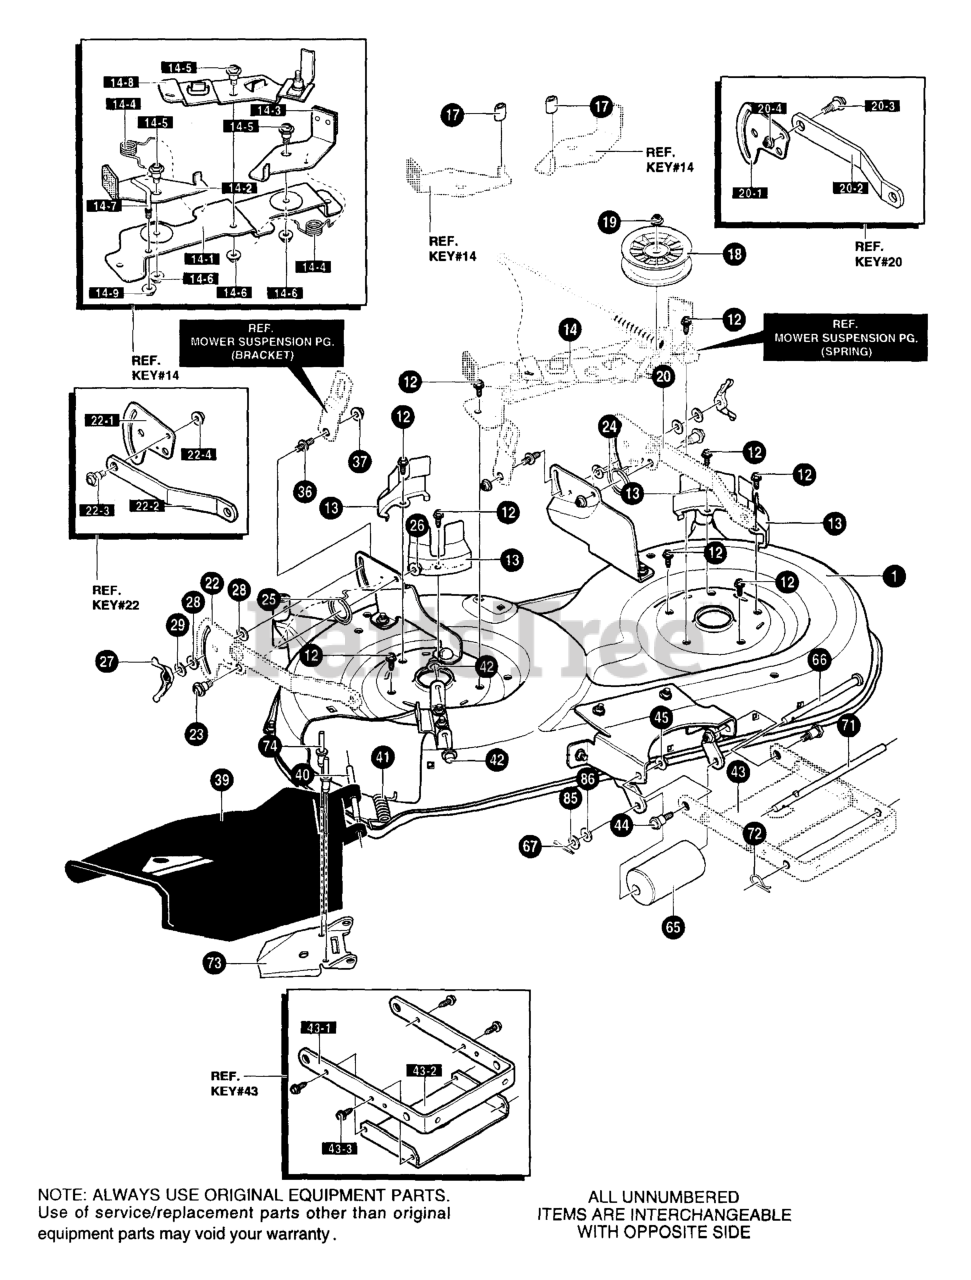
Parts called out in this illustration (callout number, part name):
1	SUB ASSY 42" MOWER DECK DELUXE
12	SCREW, 3/8-16 x 1.25 WAHHSPTAPP
13	COVER, SEGMENT BELT GUIDE
14	ASM., BRACKET SUP W/BRAKES 42"
14-1	BRACKET, BRAKE MT
14-2	ASSY, BRAKE RH
14-3	ASSY, BRAKE LH
14-4	TORSION SPRING (166X41)
14-5	BOLT.50X.75 HHSH 3/8-16 (9X39)
14-6	NUT, 3/8-16 HWDFLLK MACK (15X84)
14-7	SCREW GUIDE
14-8	ASS'Y, IDLER ARM
14-9	NUT, 5/8-16HWDFLLK
17	TUBE, BRAKE TAB PAD
18	PULLEY, IDLER BFF 4.75DIA.
19	NUT,3/8-16HWDFLLK MACK 15X84 Z
20	ASM.PLATE,REAR SUS.BRKT.LH
20-1	PLATE - SUSPENSION
20-2	SUSPENSION BRKT REAR
20-3	BOLT, SHOULDER 3/8-16 (9X52)
20-4	NUT,3/8-16HWDFLLK MACK 15X84 Z
22	ASM.PLATE,REAR SUS.BRKT.RH
22-1	PLATE - SUSPENSION
22-2	SUSPENSION BRKT REAR
22-3	BOLT, SHOULDER 3/8-16 (9X52)
22-4	NUT,3/8-16HWDFLLK MACK 15X84
23	BOLT, SHOULDER.375 (9X51)
24	SPRING,TORSION.68LG LH 166X43
25	SPRING,TORSION.68LG RH 166X42
26	NUT,3/8-16HWDFLLK MACK 15X84
27	WINGNUT, 5/16-18
28	PAD, FRICTION
29	WASHER, (17X45)
36	PIN, HANGER
37	NUT, 3/8-16 HWDFLLK MACK
39	CHUTE DEFLECTOR
40	ROD, CHUTE DEFLECTOR
41	SPRING, TORSION.44X2.06X
42	NUT, PUSH CAP .375 (28X23)
43	ASSY., BRACKET & STIFFNER
43-1	BRACKET, FRT SUSPENSION
43-2	STIFFNER
43-3	SCREW, 5/16-18 x 0.75 HHWATAP
44	BOLT, SHOULDER .375 (9X51)
45	NUT,3/8-16HWDFLLK MACK 15X84
65	ROLLER 6 X.515 I.D.X 2.5 O.D.
66	ROD, SUPPORT
67	PIN, COTTER.125 DIAX1.00LG
71	ROD HANGER
72	HAIR PIN
73	SUPPORT, DEFLECTOR
74	RIVET - SEMI .244X.250 (7X125)
85	WASHER, FLAT
86	WAVE WASHER.50ID
